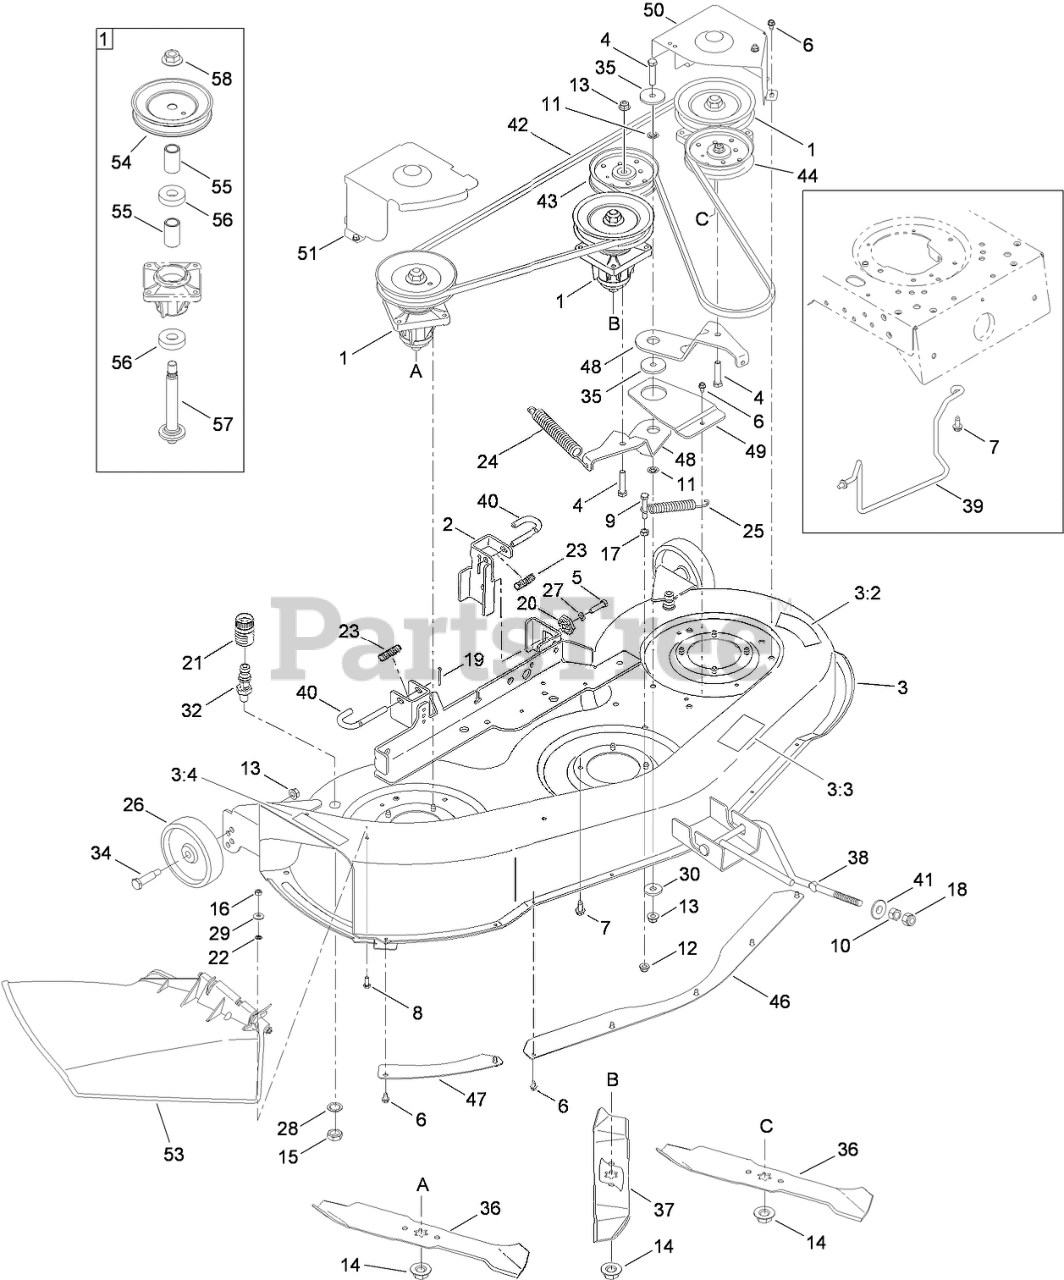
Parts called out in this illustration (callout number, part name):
1	SPINDLE ASM
2	LH HANGER BRACKET ASM
3	DECK ASM (WITH DECALS)
3:2	DECAL-DECK
3:3	DECAL-BELT ROUTING
3:4	DECAL-CHUTE
4	SCREW-HH
5	SCREW-HH
6	SCREW-HWHTF
7	SCREW-HWH
8	SCREW-HH
9	SCREW-HH
10	NUT-HEX
11	NUT-PUSH
12	NUT-LOCK, FLANGE
13	NUT-LOCK, FLANGE
14	NUT-LOCK, FLANGE
15	NUT-HEX
16	NUT-HEX
17	NUT-HEX
18	NUT-LOCK, HEX (NYLON)
19	PIN-COTTER
20	GEAR-ADJUSTMENT, DECK
21	ADAPTER-NOZZLE, WATER
22	RETAINER-BOLT
23	SPRING-COMPRESSION
24	SPRING-EXTENSION
25	SPRING-EXTENSION
26	WHEEL-DECK, REAR
27	WASHER-LOCK
28	WASHER-LOCK
29	WASHER-SPRING
30	WASHER-FLAT
32	NOZZLE-WATER, DECK
34	BOLT-SHOULDER
35	SPACER-SHOULDER
36	BLADE-16.28 INCH
37	BLADE-14.88 INCH
38	ROD-DECK
39	ROD-KEEPER, BELT
40	PIN-HANDLE, DECK RELEASE
41	CUP-PIVOT, LIFT
42	BELT-TYPE A
43	PULLEY-IDLER, 4.25 INCH
44	PULLEY-IDLER, 3.50 INCH
46	SKIRT-CENTER, DECK
47	SKIRT-RH, DECK
48	BRACKET-IDLER
49	BRACKET-SUPPORT
50	COVER-BELT
51	COVER-BELT
53	CHUTE ASM
54	PULLEY-DECK
55	SPACER
56	BEARING-BALL
57	SHAFT-SPINDLE
58	NUT-LOCK, FLANGE
